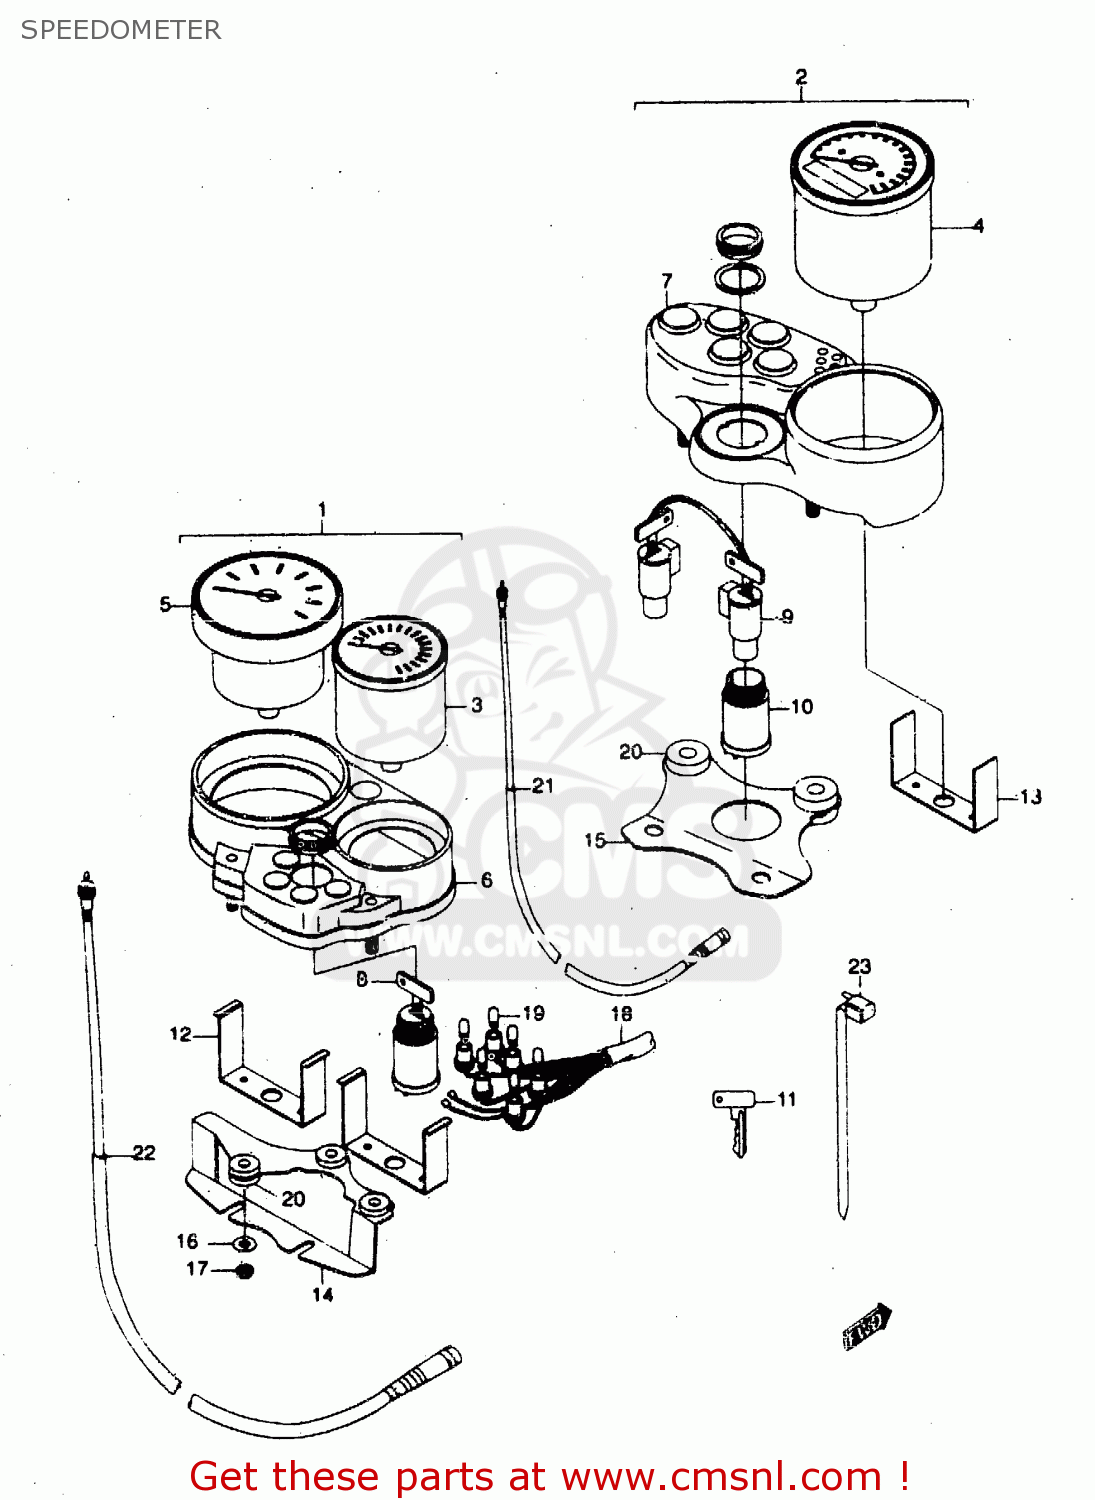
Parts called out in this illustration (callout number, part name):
1	SPEEDOMETER ASSY
2	SPEEDOMETER ASSY
3	SPEEDOMETER
4	SPEEDOMETER
5	TACHOMETER
6	HODD, METER
7	HODD, METER
8	KEY ASSY
9	KEY
10	BODY ASSY, KEY
11	KEY, BLANK
12	BRACKET
13	BRACKET
14	BRACKET
15	BRACKET
16	WASHER
17	NUT
18	HARNESS
19	SOCKET AND BULB
20	CUSHION
21	CABLE ASSY, TACHOMETER
22	CABLE,SPEEDOME
23	CLAMP(L:125)
